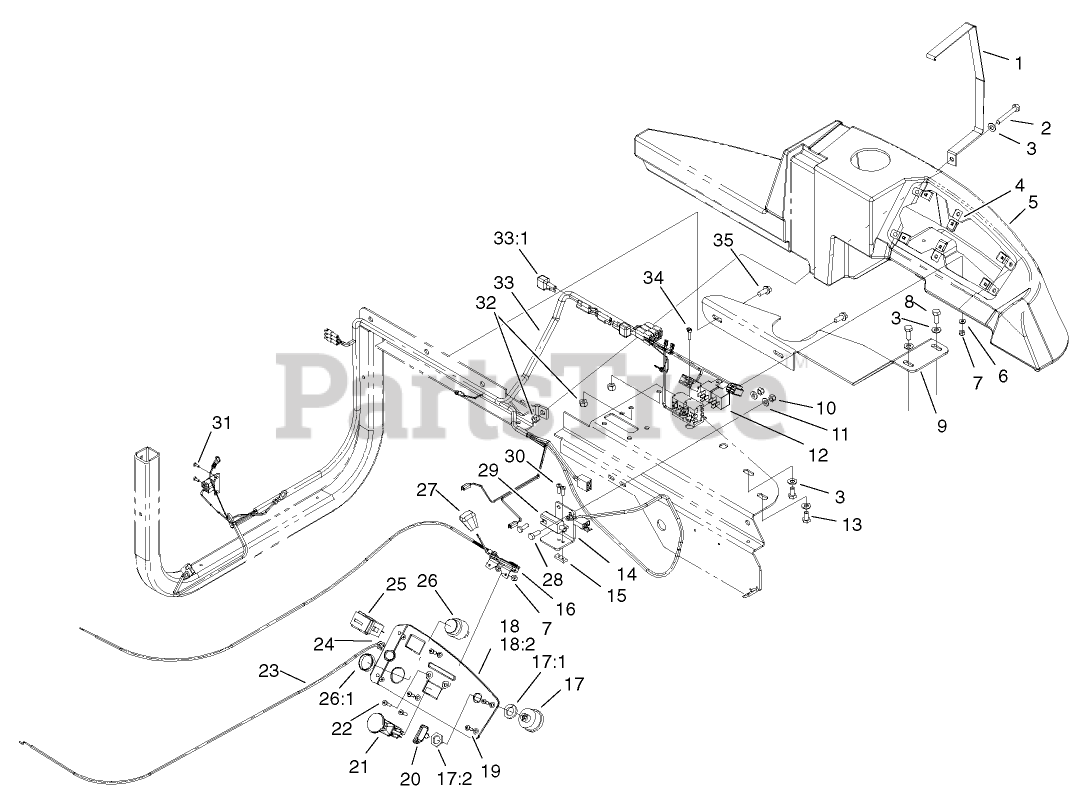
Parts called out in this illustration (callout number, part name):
1	STRAP-CONSOLE
2	SCREW-HH
3	WASHER-PLAIN
4	CLIP-TINNERMAN
5	CONSOLE
6	WASHER-FLAT
7	NUT-LOCK, NI
8	SCREW-HH
9	PLATE-SUPPORT, CONSOLE
10	NUT-LOCK, NI
11	WASHER-FLAT
12	RELAY
13	SCREW-HH
14	BRACKET-SWITCH
15	PLATE-TAPPED
16	THROTTLE CONTROL ASM
17	Key Switch ASM
17:1	WASHER-TOOTH, INTERNAL
17:2	NUT-HH
18	Instrument Panel ASM
18:2	Decal-Instrument
19	SCREW-PPH
20	KEY-IGNITION
21	SWITCH-DELTA
22	SCREW-PPH
23	CONTROL-CHOKE
24	NUT-HJ
25	HOURMETER
26	AUDIO ALARM ASM
26:1	NUT-PLASTIC, KNURLED
28	SCREW-HH
29	SWITCH
30	SCREW-PPH
31	SCREW-TAP
32	NUT-LOCK, NI
33	HARNESS-WIRE
34	SCREW-HWH
35	SCREW-HWHTF
